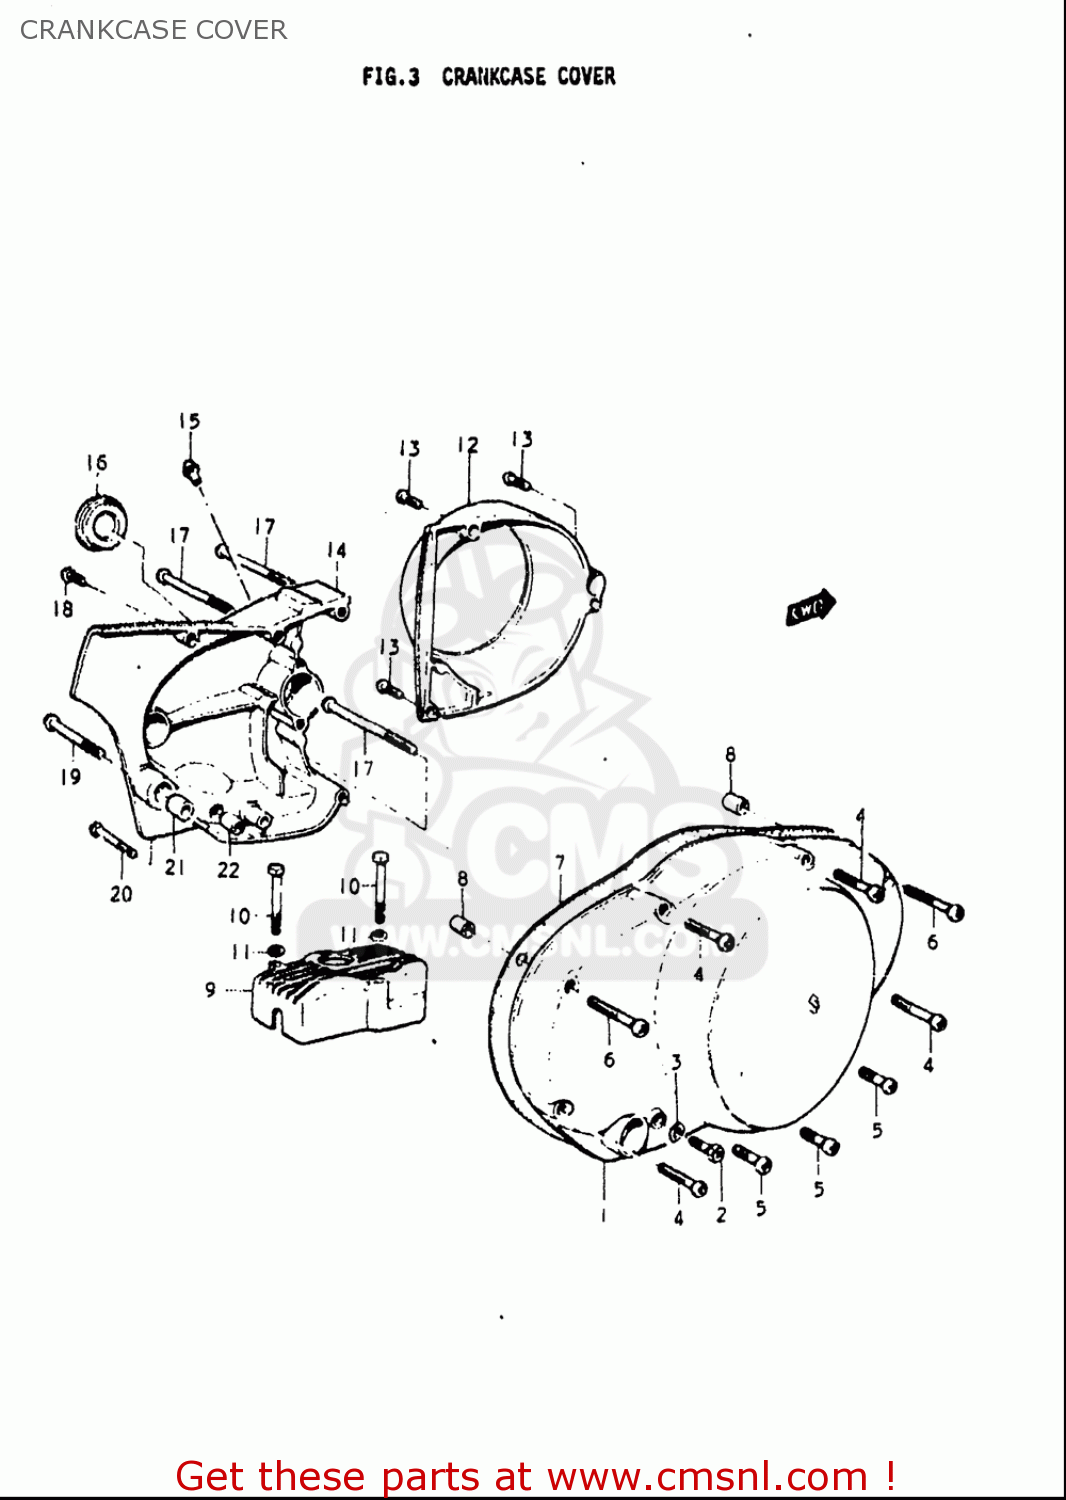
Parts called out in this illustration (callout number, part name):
2	SCREW(6X10)
3	GASKET(6.2X11X1) (NAS)
4	SCREW
5	SCREW
6	SCREW
7	GASKET,CLUTCH COVER (NAS)
8	PIN
10	BOLT(6X35)
11	WASHER
13	SCREW
15	NIPPLE
16	CAP(OD:36)
17	SCREW
18	SCREW
19	SCREW
20	SCREW
21	PIN
